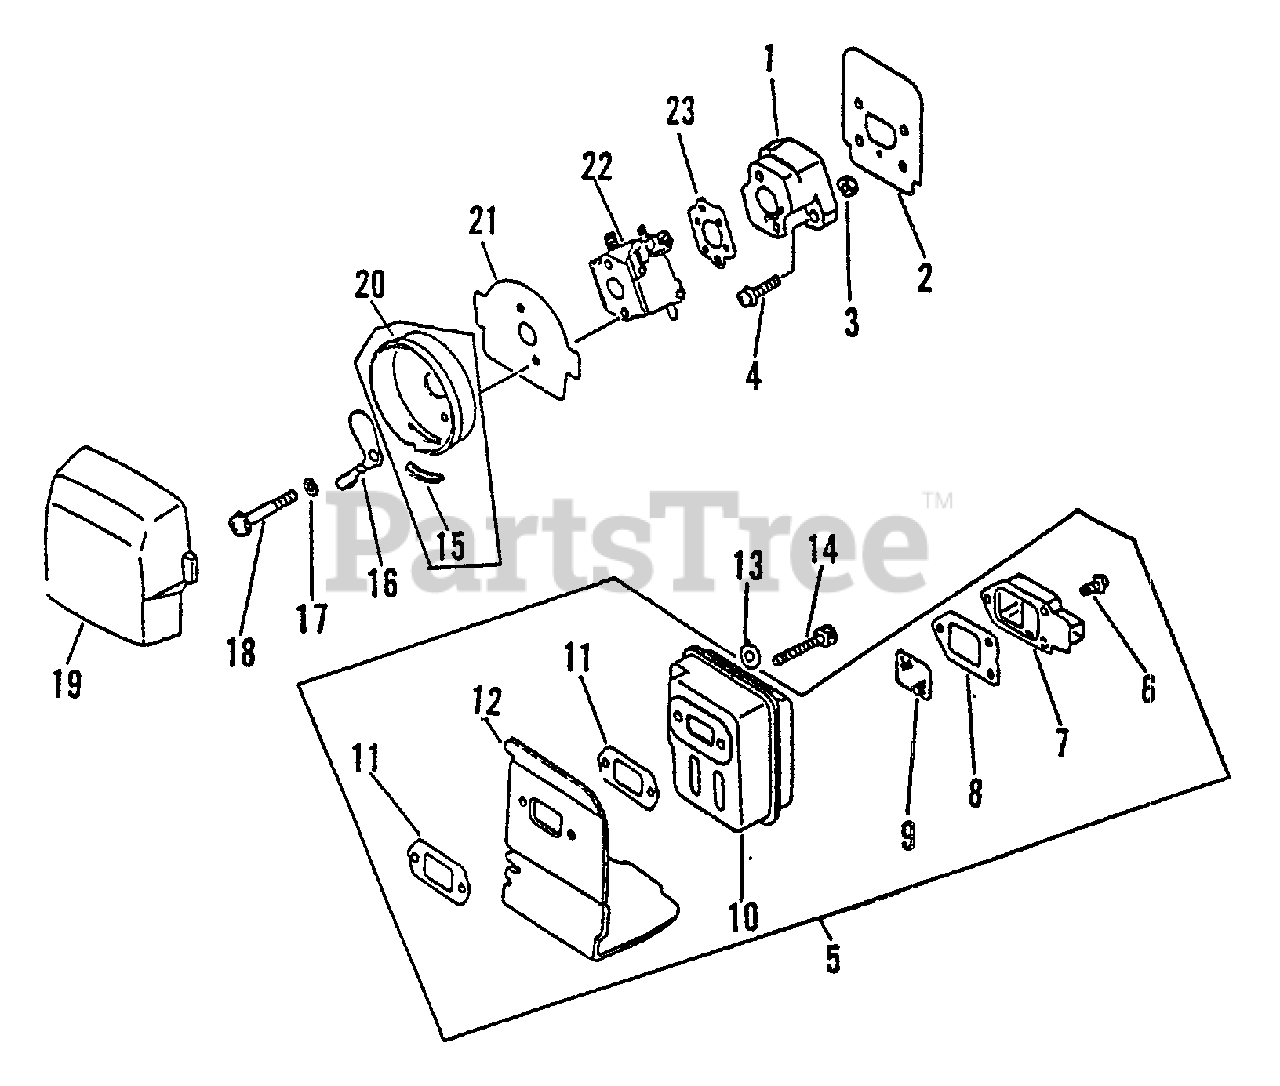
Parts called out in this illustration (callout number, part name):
1	INSULATOR, INTAKE
2	HEAT SHIELD, INTAKE
3	NUT M5
4	SCREW 5×20
5	MUFFLER ASSY
6	SCREW 4×10
7	GUIDE, EXHAUST - INNER
8	GASKET, EXHAUST
9	SCREEN, SPARK ARRESTER
11	GASKET, EXHAUST
12	COVER, EXHAUST
13	WASHER, FLAT 5.5×10×0.8
14	BOLT 5×55
16	SHUTTER, CHOKE
17	WASHER 5.2×8×0.8T
18	SCREW 5×57
19	FILTER, AIR
20	CASE, AIR FILTER
21	PLATE, AIR FILTER
22	CARBURETOR - C1U-K9
23	GASKET, INTAKE
